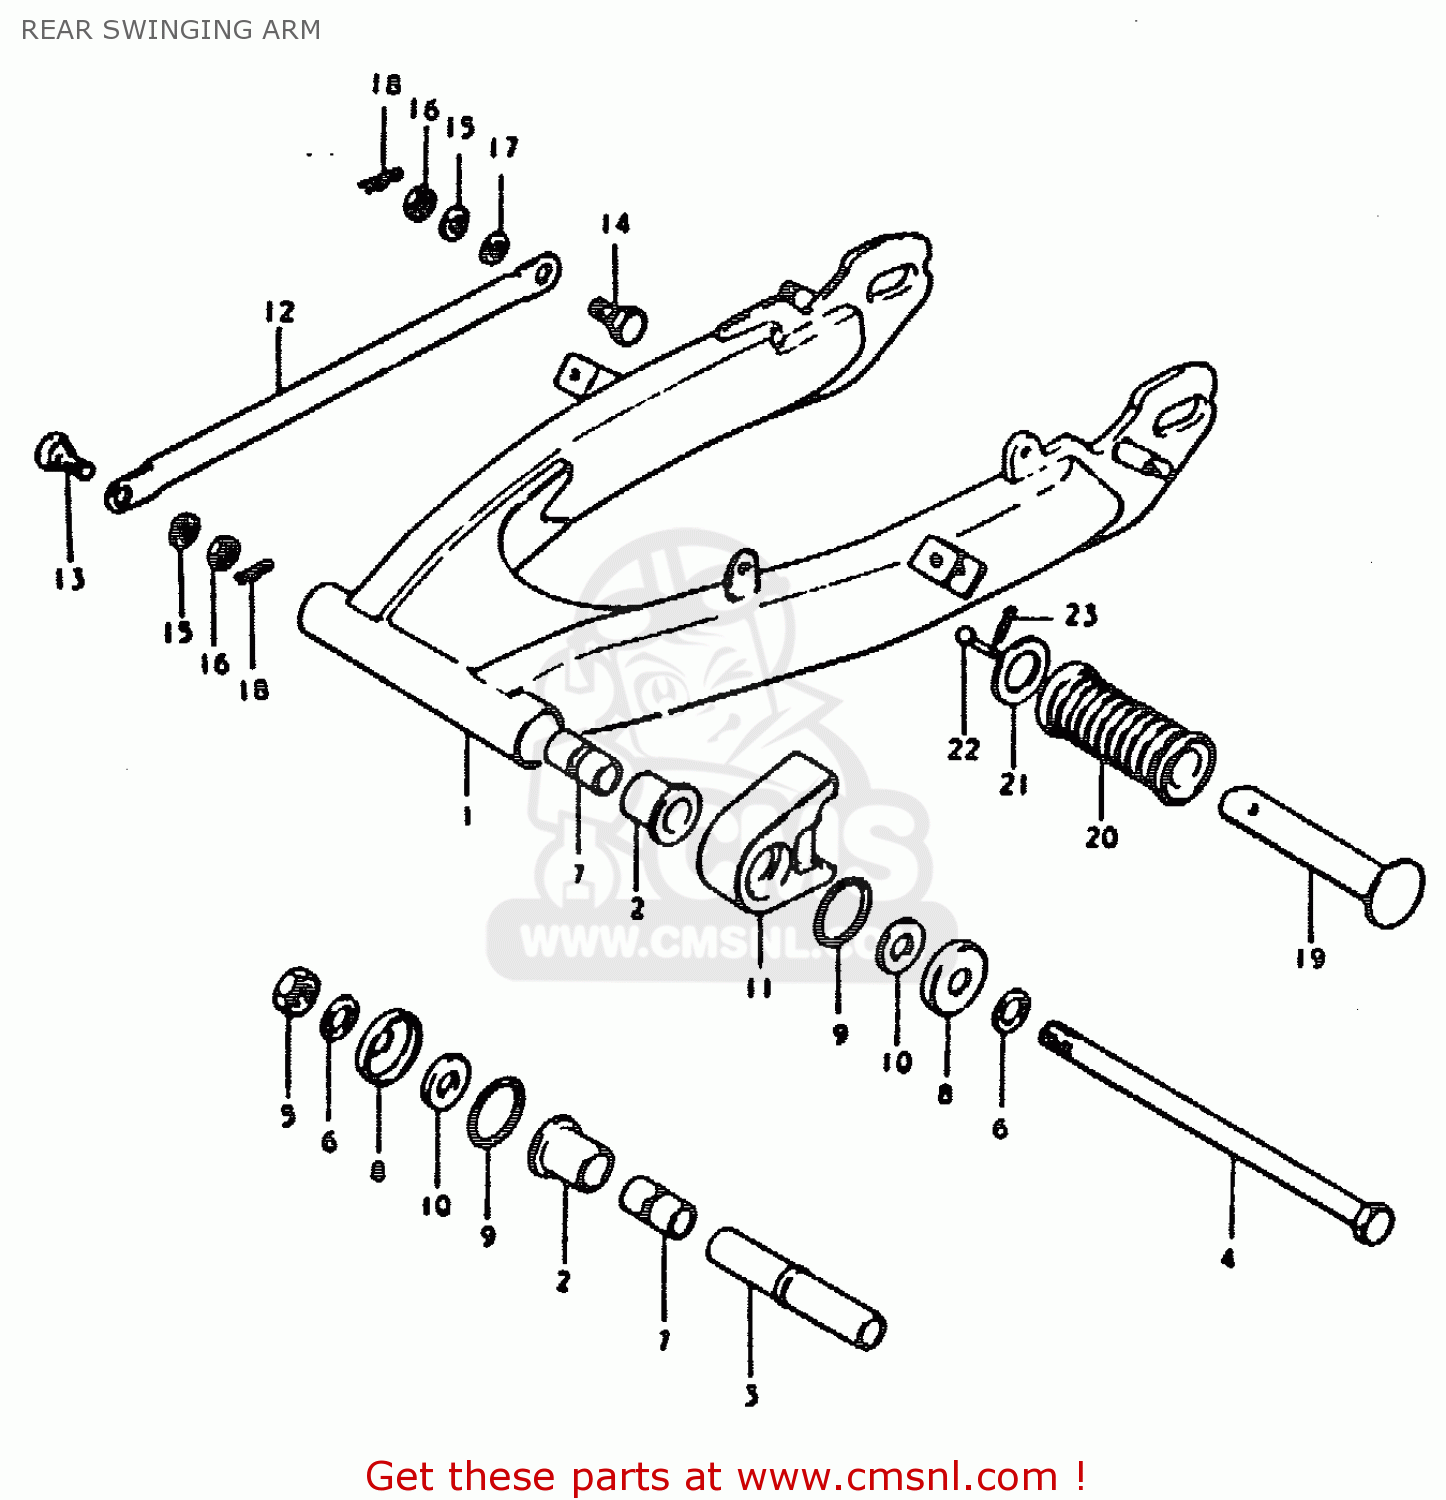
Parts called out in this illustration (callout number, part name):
1	SWING ARM ASSEMBLY,REAR
2	BUSH
3	SPACER,RR SWGARM PIVOT CTR
4	SHAFT,REAR SWING ARM
5	NUT 12MM
6	WASHER
7	SPACER,RR SWGARM PIVOT
8	COVER,SWGARM BUSH DUST SEAL
9	O RING(D:2,ID:24.5)
10	WASHER(12.5X24X2.3)
11	BUFFER,CHAIN TOUCH DEFLECTOR
12	TORQUE LINK, REAR
13	BOLT(8X22)
14	BOLT(8X26.5)
15	LOCK WASHER
16	NUT
17	WASHER
18	CLIP
19	BAR,FOOTREST RUBBER
20	RUBBER,PILLION FOOTREST
21	WASHER (19.5X32X2)
22	PIN
23	PIN 20X20
